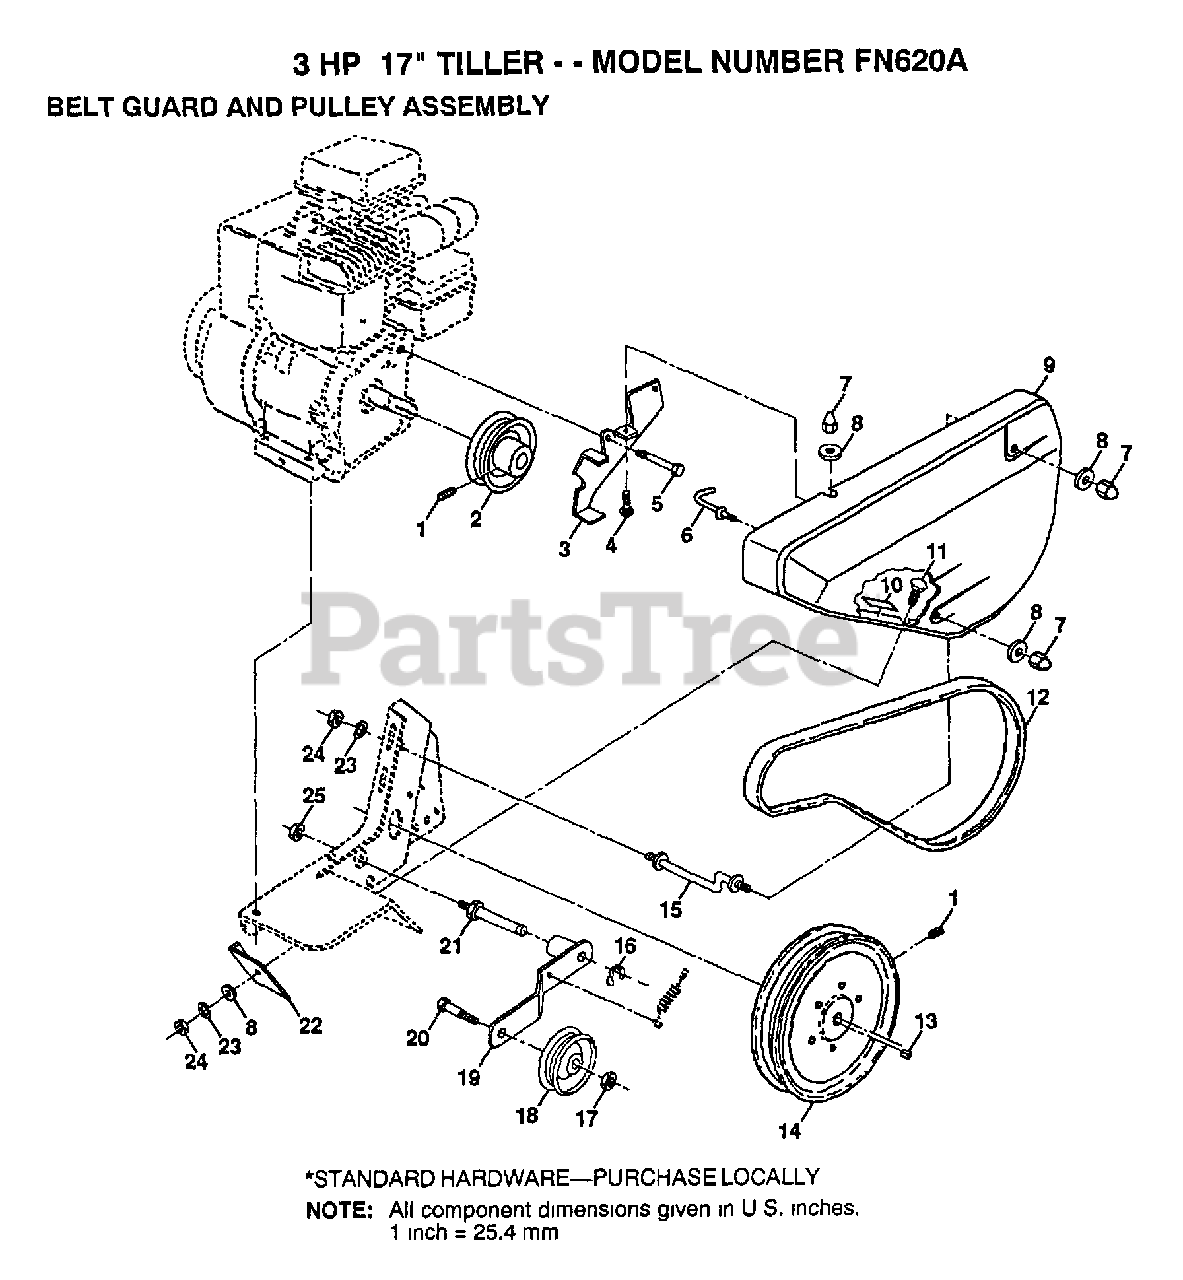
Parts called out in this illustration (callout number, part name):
1	SET SCREW
4	BOLT
7	NUT-CAP TI
8	WASHER
10	PAD IDLER TI
11	BOLT T
13	KEY T
14	TRANS SHEAVE RT
16	KLIP RING TI
17	NUT
19	IDLER ARM TI
21	SHAFT IDLER TI
22	SHIELD-DIRT TI
23	LOCKWASHER
25	JAM NUT TI
